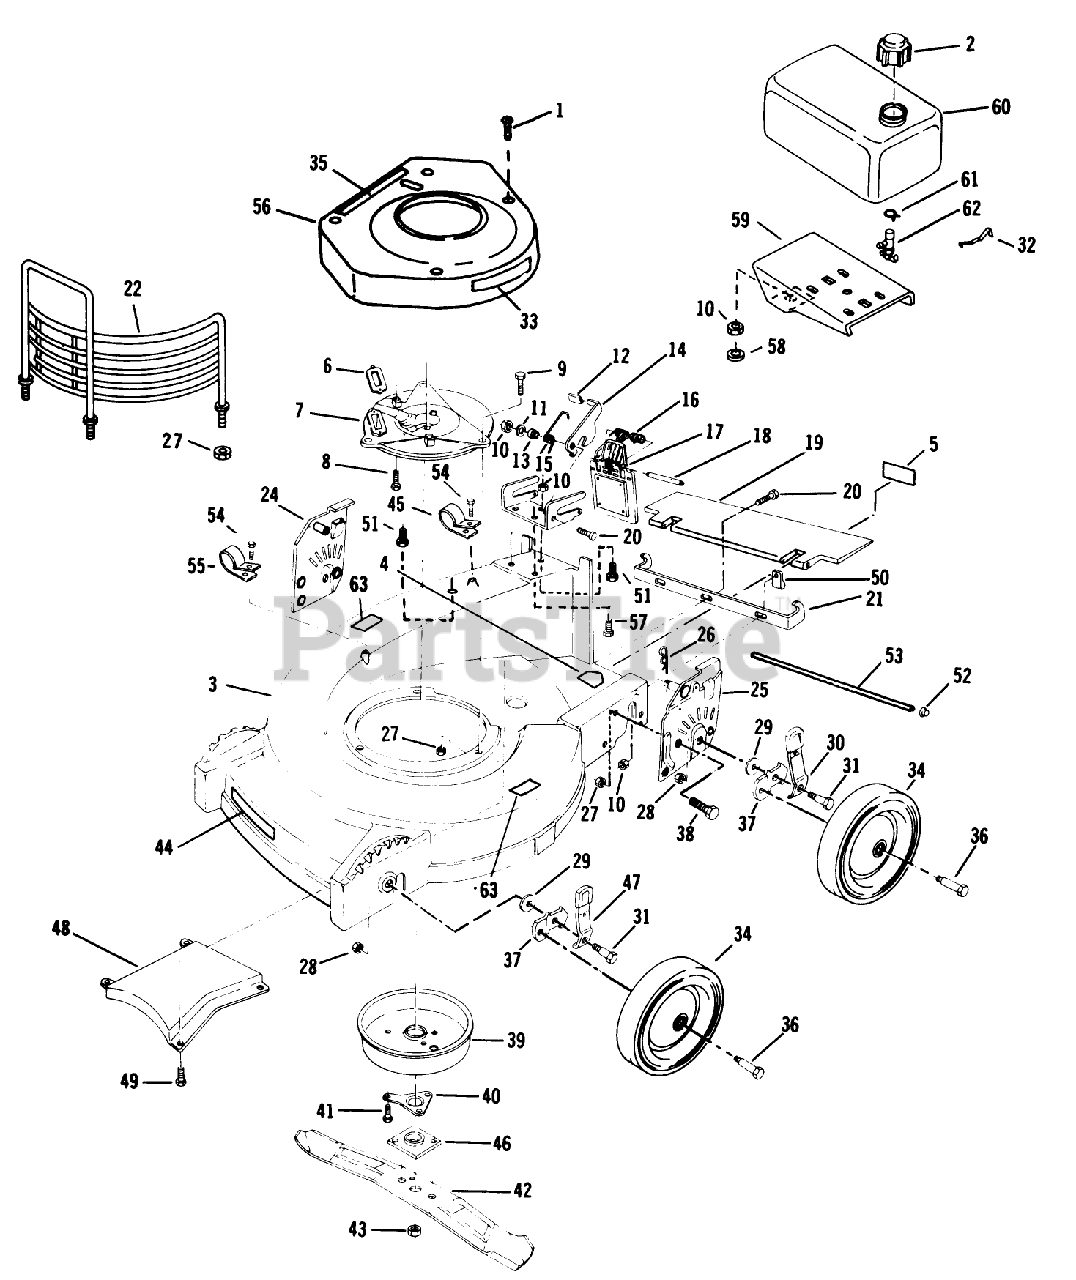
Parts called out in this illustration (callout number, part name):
1	SCREW - SELF TAPPING
2	FUEL CAP & INSERT
8	SCREW V
9	SCREW-HH
10	LOCKNUT E
15	SPRING
16	SPRING ASOC
18	ROD (RB&W)
19	T/SHIELD SM&P
26	HAIR PIN
27	NUT-LOCK F
28	LOCKNUT
29	WASHER
31	BOLT
32	SPRING
34	WHL & TIRE AY
36	BOLT-SHOULDER
39	MUFFLER COVER F
40	SUPPORT F
41	SCREW
43	NUT-BLADE
46	PLATE AND COLLAR ASM
48	BAFFLE CHUTE PL
51	SCREW HEX WASHER
54	SCREW LAWRENCE
56	SHROUD S
57	SCREW
58	WASHER
61	CLAMP - HOSE S
62	VALVE&SCREEN SM
